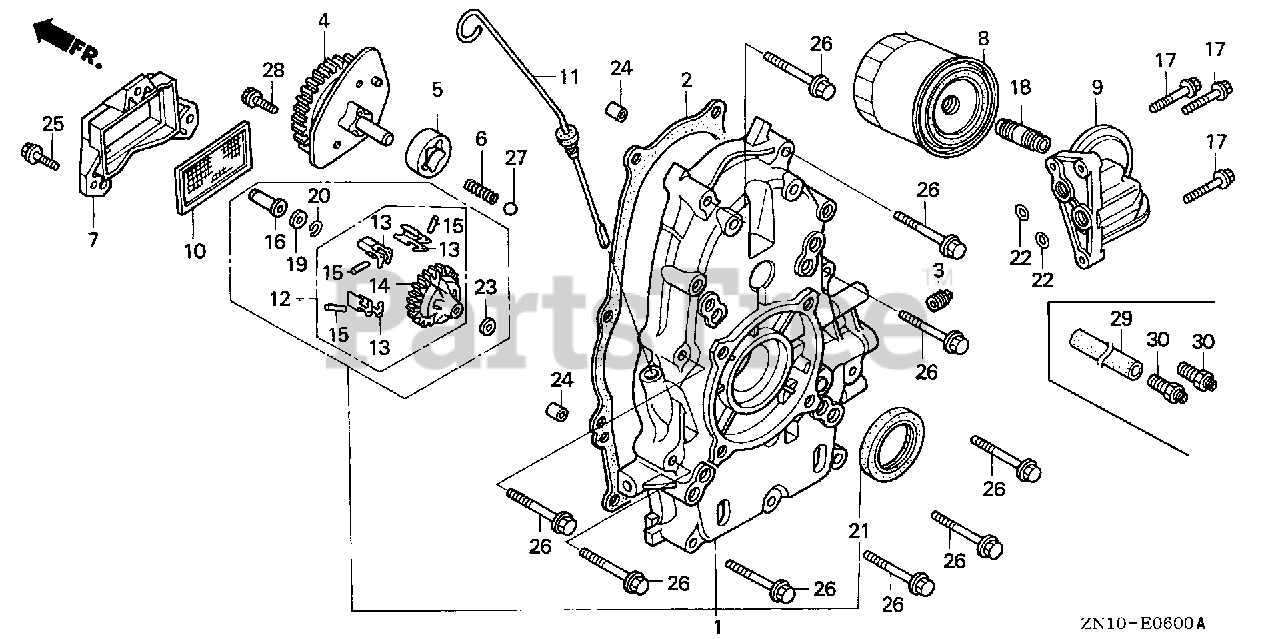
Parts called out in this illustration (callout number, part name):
1	COVER ASSY., CRANKCASE
2	GASKET, CASE COVER
3	BOLT, SEALING
4	COVER ASSY., OIL PUMP (THREE BOLTS)
5	ROTOR, OIL PUMP (OUTER)
6	SPRING, RELIEF VALVE
7	COVER, OIL FILTER
8	FILTER, OIL (FILTECH TOYO ROKI) (SOLD INDIVIDUALLY)
8	FILTER, OIL (TOYO ROKI) (SOLD INDIVIDUALLY)
9	BASE, OIL FILTER
10	SCREEN, OIL FILTER
11	DIPSTICK, OIL
12	GOVERNOR ASSY.
13	WEIGHT, GOVERNOR
14	HOLDER, GOVERNOR WEIGHT
15	PIN, GOVERNOR WEIGHT
16	SLIDER, GOVERNOR
17	BOLT, FLANGE (6X28) (CT200)
18	HOLDER, OIL FILTER
19	WASHER (6X16)
20	CLIP, GOVERNOR HOLDER
21	OIL SEAL (38X58X9)
22	O-RING (11.8X2.4)
23	WASHER, PLAIN (6MM)
24	PIN, DOWEL (8X14)
25	BOLT, FLANGE (6X20)
26	BOLT, FLANGE (8X50)
27	BALL, STEEL (#12) (3/8)
28	BOLT, SOCKET (6X16)
